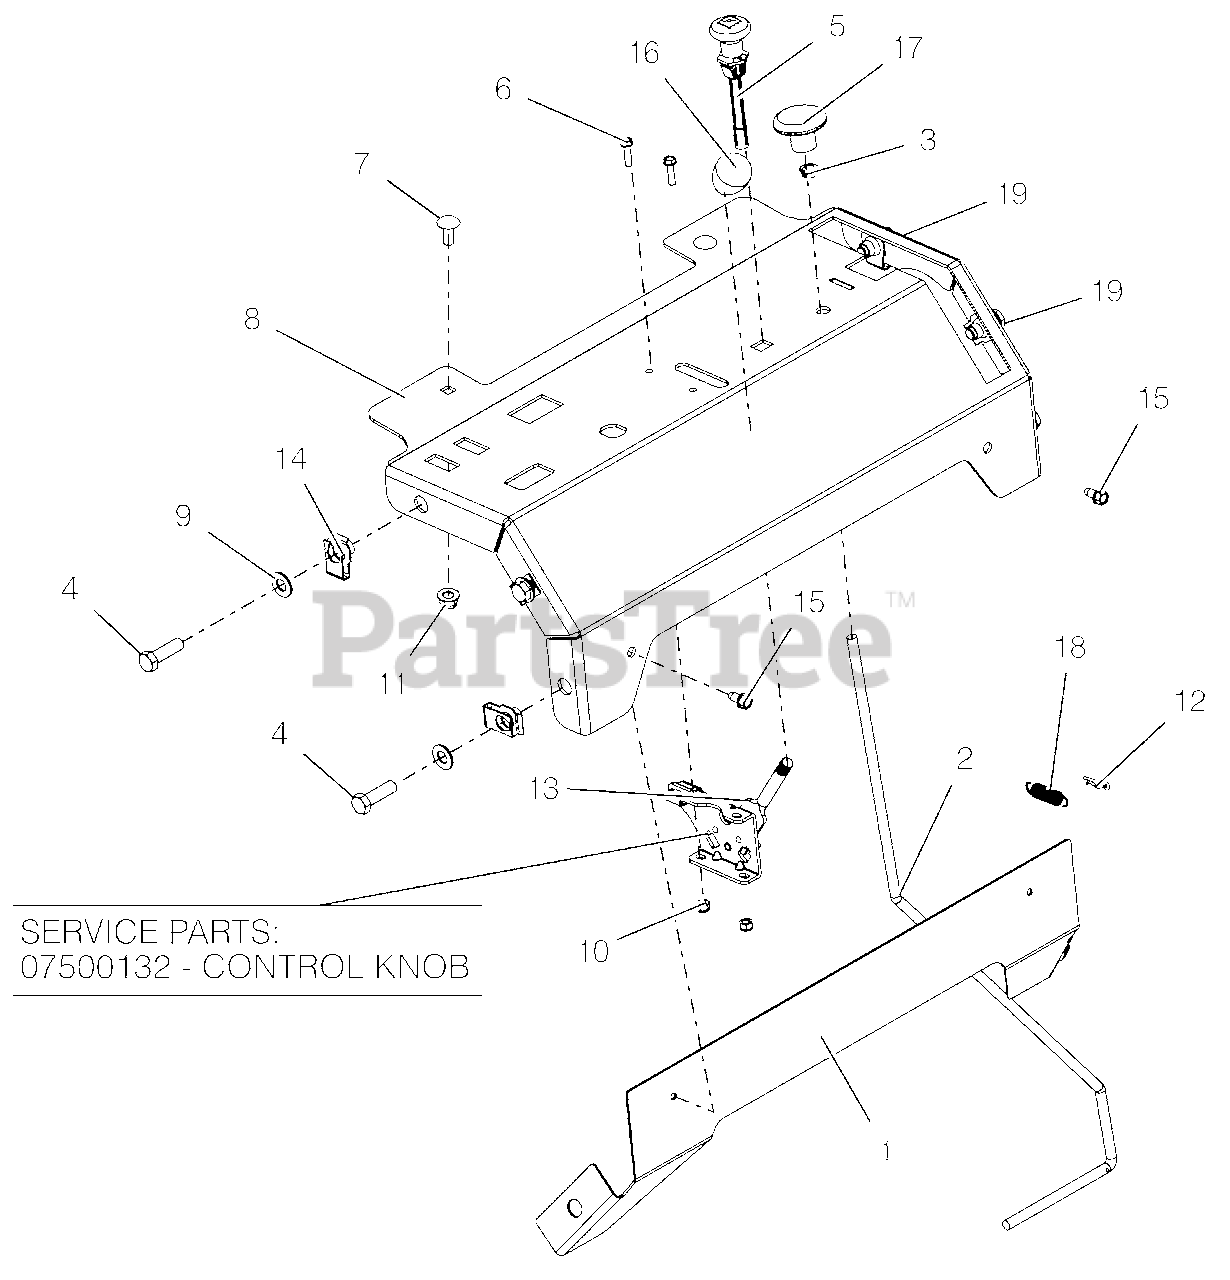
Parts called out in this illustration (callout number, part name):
1	PLATE, FRONT BACKER
2	WIREFORM, TRAILER LOCK
3	BUSHING, POLYLINER-.38 SNAPIN
4	@BLT-HEX .38-16X1.25 GR5 YWZC
5	CABLE, CHOKE (SNAP IN)
6	@SCR-MCH 10-24X.75 HWH YWZC
7	@BLT-RHDSSQNK .31-18X.75 G5YZ
8	KIT, SERVICE COMP. STANCE DASH
9	@WSHR-FL-STL.406X.812X.065 YWZ
10	@NUT-LK-NYL 10-24 W/INSRT YWZC
11	@NUT-LK-NYL-FLG .31-18 YWZC
12	PIN-HAIR, ENDRIES #25 YWZC
13	CABLE, PRO-CONTROL
13	KNOB-CONTROL-BLACK .38-16X.50
14	NUT-RTNR .375-16X.37
15	SCR-TAP .25-20X.50 HWH TR YWZ
16	KNOB-CONTROL-BLACK .38-16X.50
17	KNOB, PUSH-PULL .312-18
18	SG-TENS .048X.44X1.75 WLD 9
19	@BLT-HEX .38-16X1.00 GR5 YWZC
